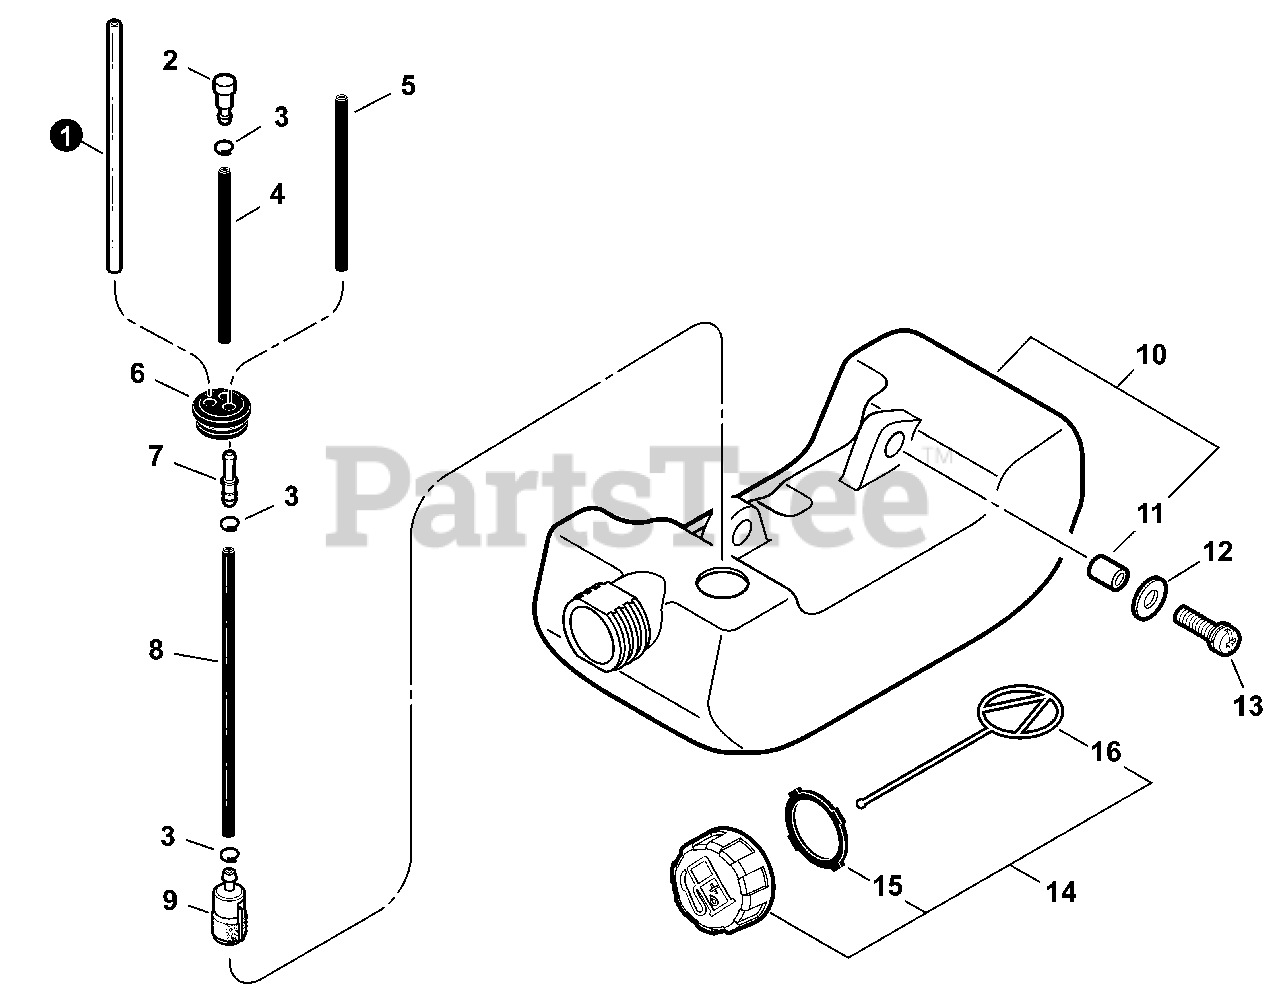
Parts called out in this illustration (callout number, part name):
1	PIPE, FUEL RETURN 3×6×90 MM
2	VENT ASSY
3	CLIP Ø6
4	PIPE, FUEL 3×5×70 BLACK
5	PIPE, FUEL 3×5×74 BLACK
6	GROMMET, FUEL Ø5
7	CONNECTOR, PIPE Ø5ר3.5
8	PIPE 3×5×110
9	FILTER, FUEL
10	TANK, FUEL
11	SPACER 6.2×7.8×6
12	WASHER 5.5×12×0.8
13	BOLT 5×16
14	CAP ASSY, FUEL
15	GASKET, FUEL CAP
16	CONNECTOR, CAP L= 100 MM
